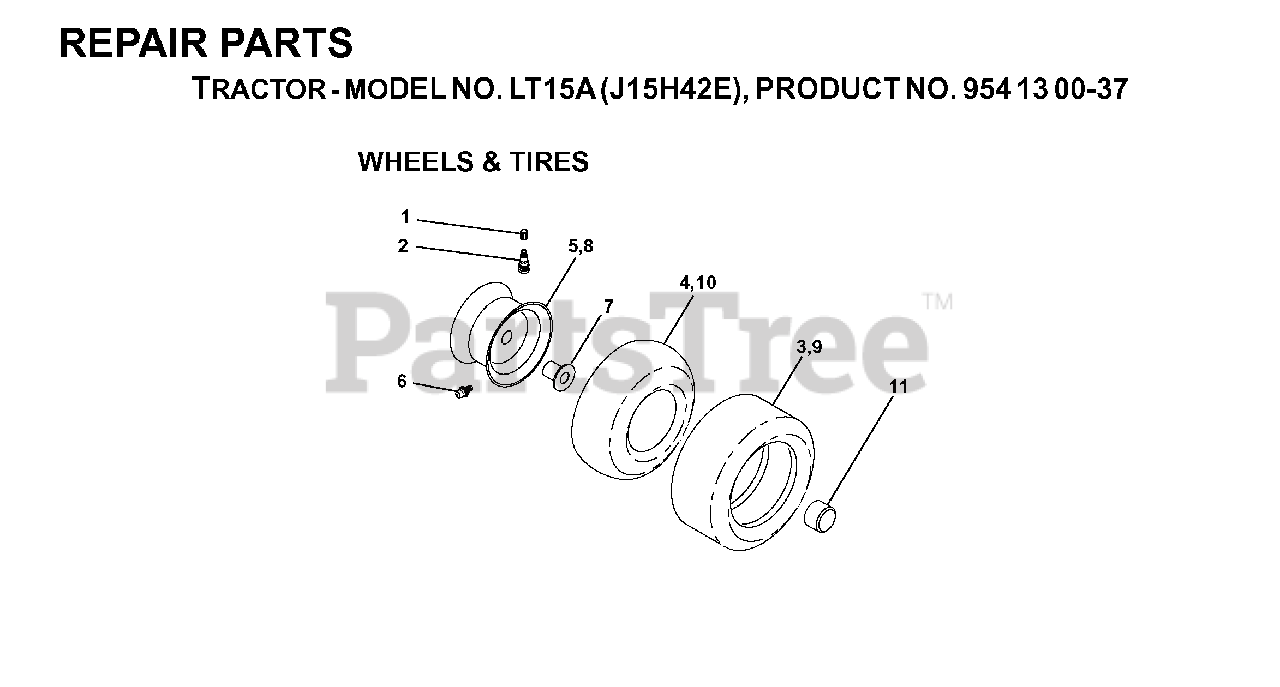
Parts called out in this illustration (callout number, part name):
1	VALVE CAP
2	VALVE STEM LT
3	TIRE HEAVY DUTY
4	TUBE.5.3/4.5/6
5	RIM ASM 6" FRONT SILVER
6	FITTING LT
7	BEARING T
8	RIM ASM 8" REAR SILVER
9	TIRE.TS.20X10-8
10	TUBE
11	CAP-HUB FRONT LT
